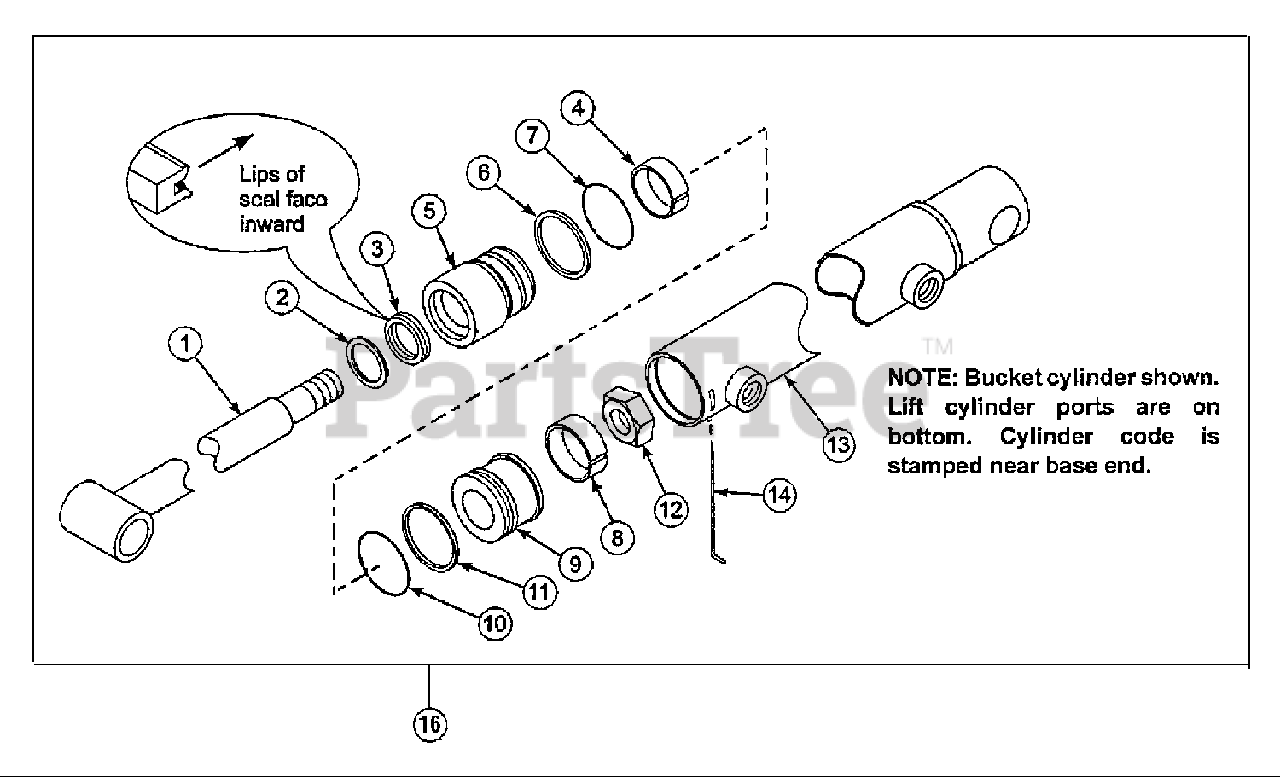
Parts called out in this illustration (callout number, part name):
1	ROD, Cylinder, 1"
5	HEAD, Cylinder
12	NUT, Hex Lock, 3/4-10
13	TUBE, Cylinder
15	REPAIR KIT, (Contains Ref. Nos. 2-4, 6-8, 10, 11 & 14)
16	CYLINDER BUCKET, Complete
